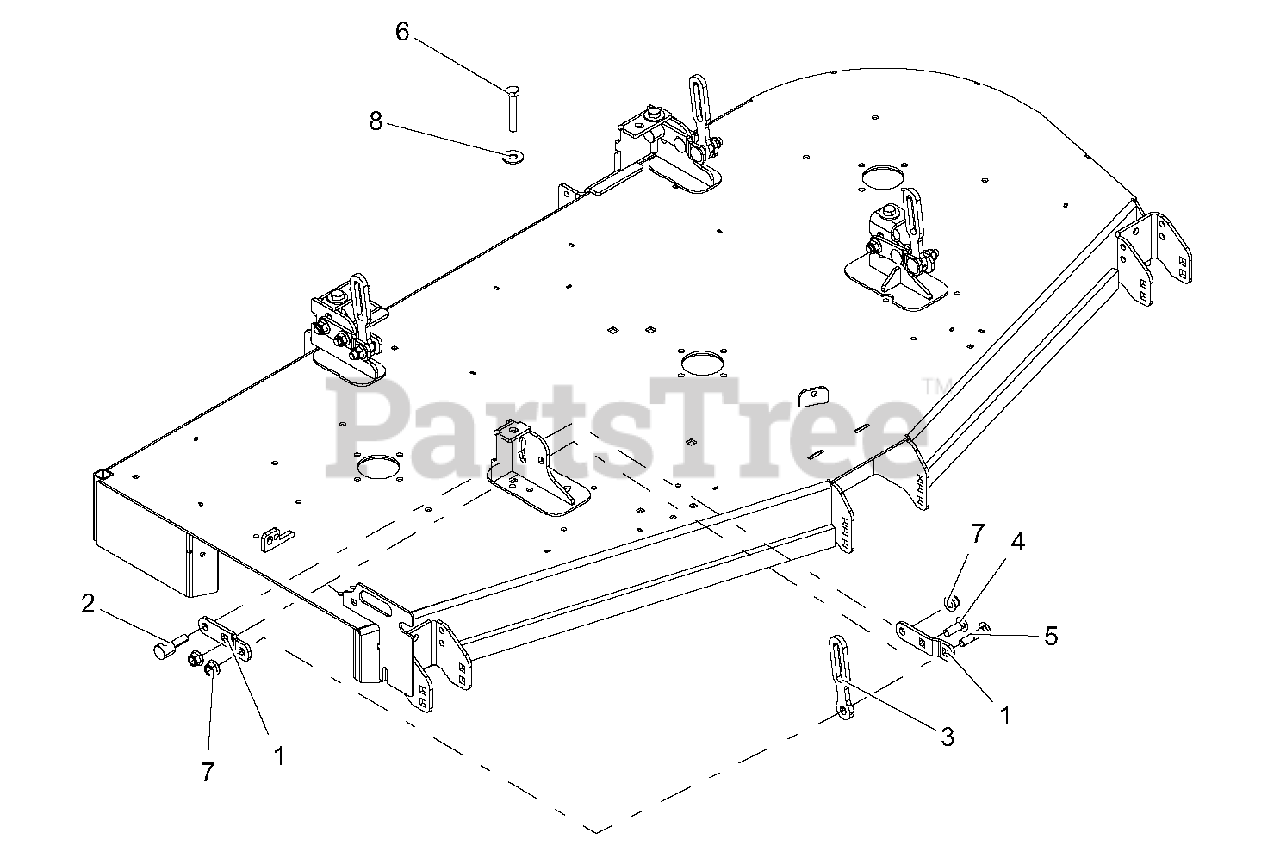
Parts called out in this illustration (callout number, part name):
1	BRKT, DECK LEVELING-BLACK
2	TRUNNION, .50-13
3	LINK, DECK LIFT
4	@BLT-RDHDSQNK .50-13X1.50 G5 YWZC
5	BLT-RDHDSQNK .50-13X2.25 G5
6	BLT-HEX .50-13X3.00 GR5 FTH YWZC
7	NUT-LK-NYL-FLG .50-13 YWZC
8	@WSHR-FL-STL.563X1.38X.109YWZC
